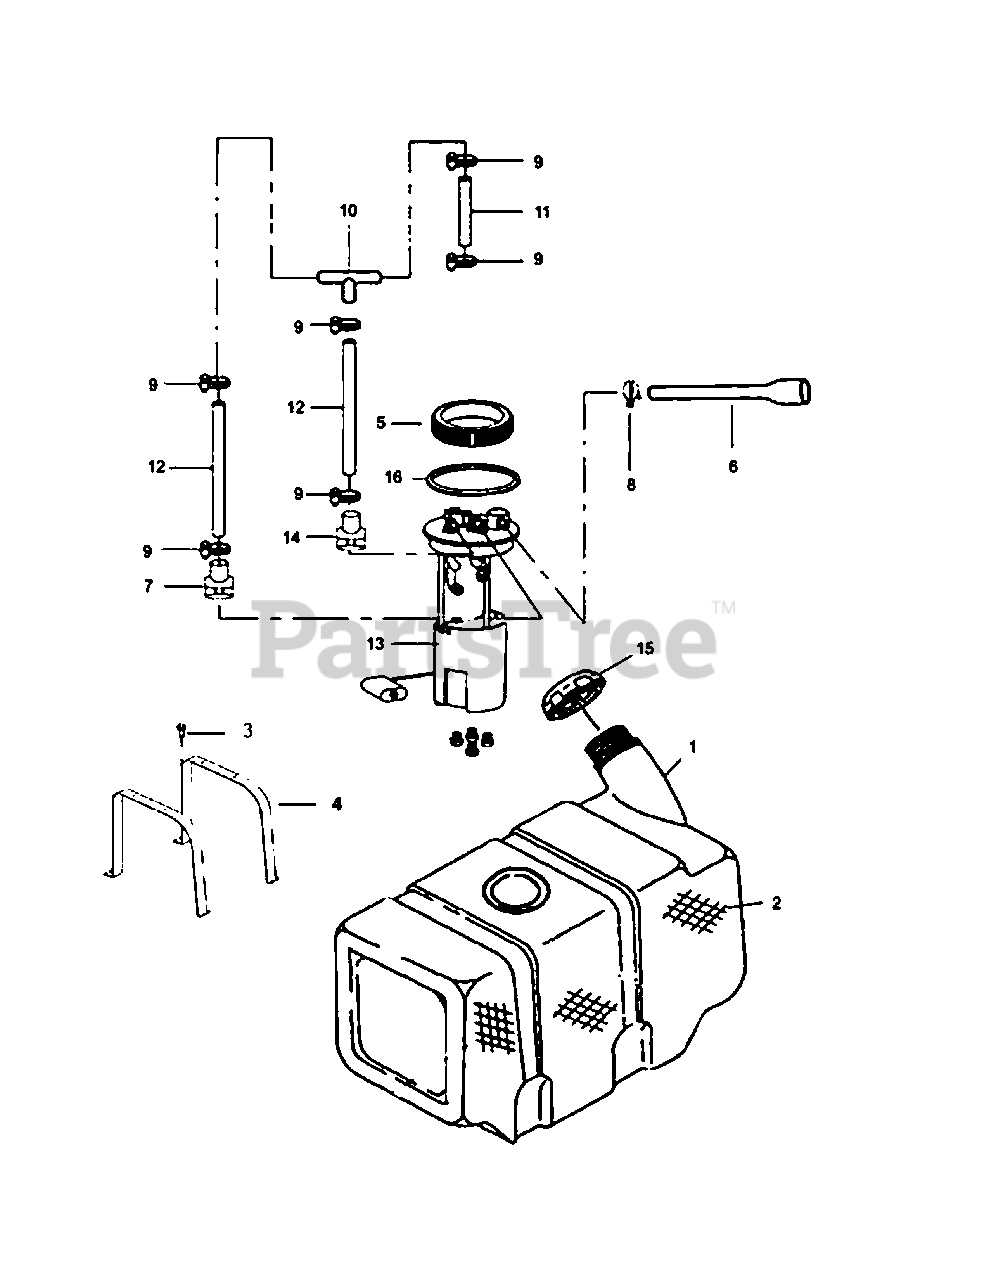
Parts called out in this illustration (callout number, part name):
1	Fuel Tank
2	Insulation Paper
3	Hexagon Flange Bolt M8×20
4	Binder Plate, Fuel Tank
5	Cover, Fuel Pump(EFI Engine)
6	Rubber Tube VI (EFI Engine)
7	Plug For Fuel Outlet(EFI Engine)
8	Clip10
9	Clip
10	Fuel Three-way Pipe
11	High-pressure Fuel Pipe 8×14-885
12	Fuel Pipe 8×14-330(EFI Engine)
13	Fuel Pump Assy(EFI Engine)
14	Plug, Fuel Inlet(EFI Engine)
15	Fuel Tank Cap
16	Seal Gasket For Fuel Pump(EFI Engine)
17	Hexagon Flange Bolt M8×20
